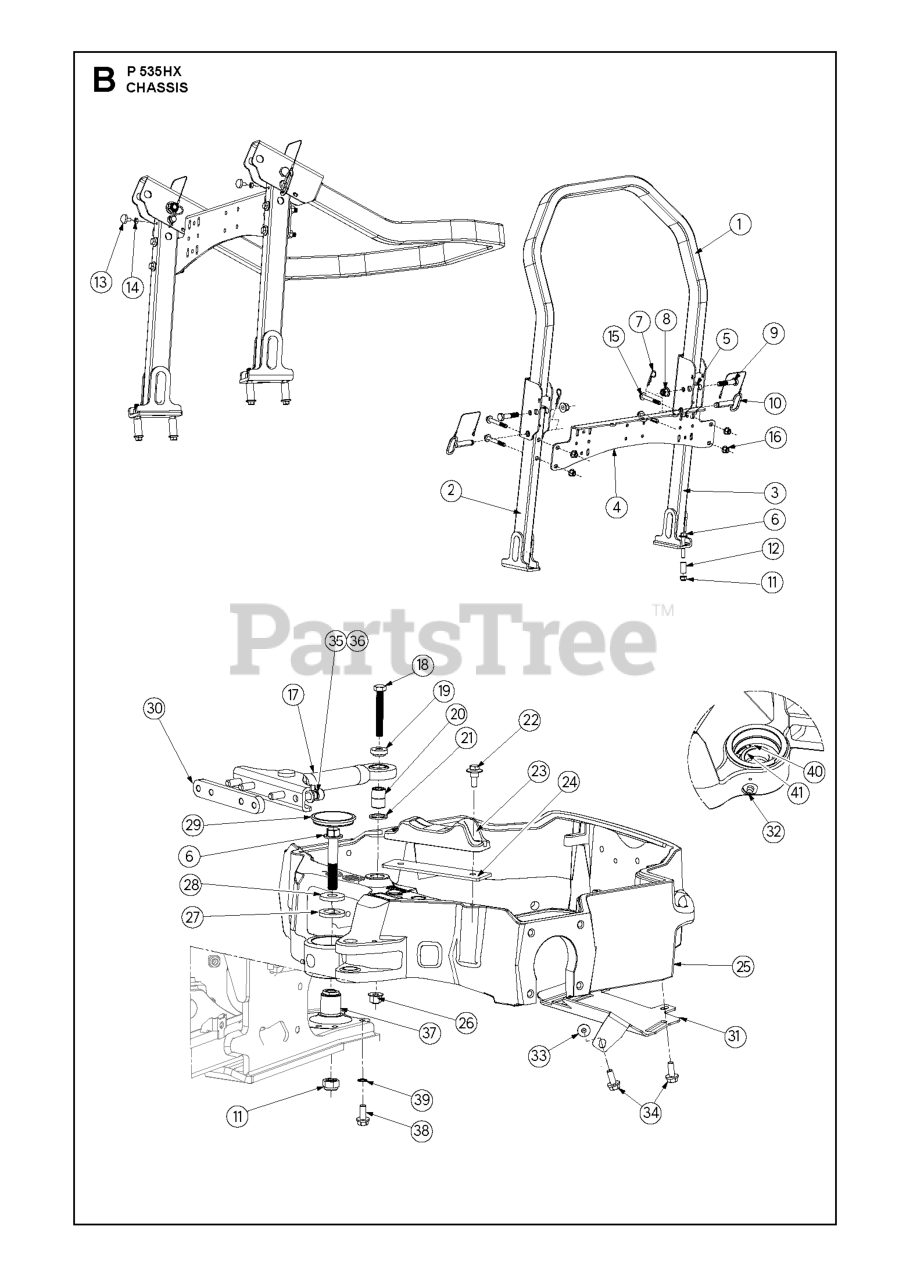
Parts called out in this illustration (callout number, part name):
13	ANTIVIBRATION ELEMENT
14	NUT
22	COLLAR SCREW
32	GREASE NIPPLE
33	NUT FLANGE
35	SCREW IHSCM M10X30 12.9 ZPB L
36	WASHER
